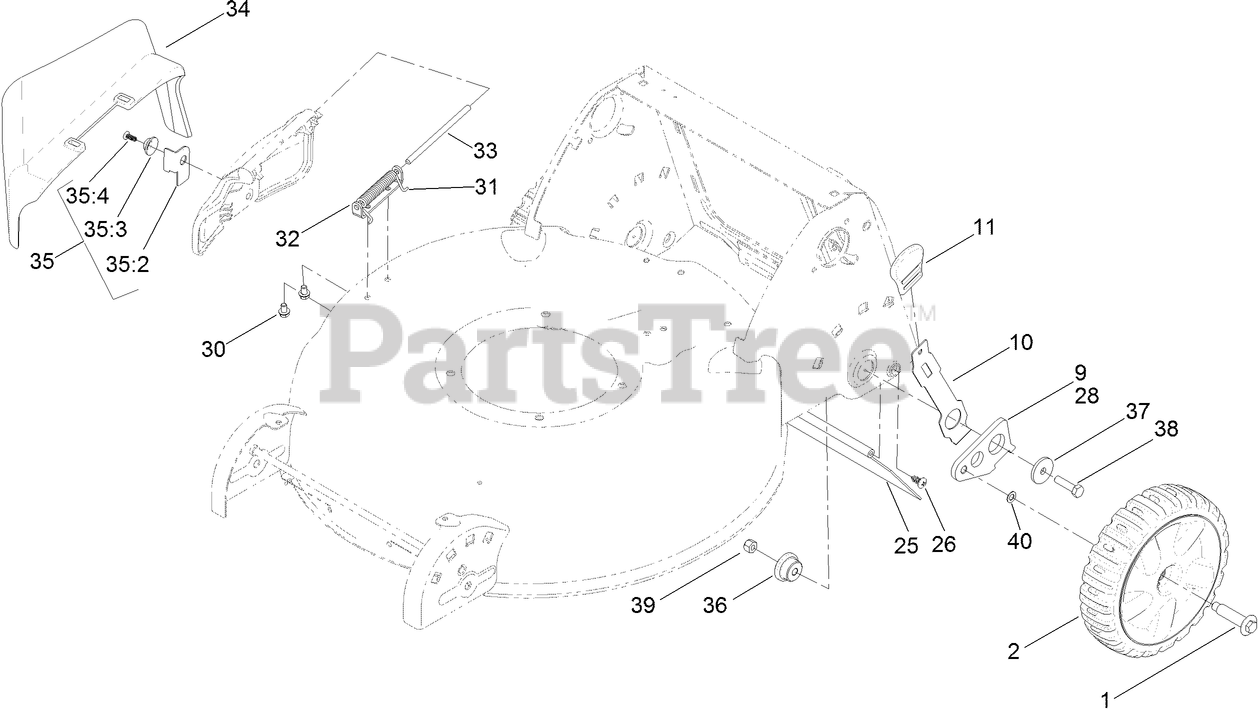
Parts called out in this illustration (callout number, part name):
1	BOLT-SHOULDER
2	8 INCH WHEEL AND TIRE ASM
9	ARM-REAR PIVOT, LH
10	ARM-SPRING, REAR
11	KNOB-HOC
25	SHIELD-TRAILING
26	SCREW-PTH
28	ARM-REAR PIVOT, RH
30	SCREW-HWH
31	SPRING-TORSION
32	BRACKET-COVER
34	CHUTE-DISCHARGE, SIDE
35	DISCHARGE DOOR ASM
35:2	LATCH-DOOR
35:3	CAP-DOOR
35:4	SCREW-PLASTITE
36	BUSHING-MOUNT, HOC
37	WASHER-FLAT
38	SCREW-HH
39	NUT-LOCK, NI
40	WASHER
